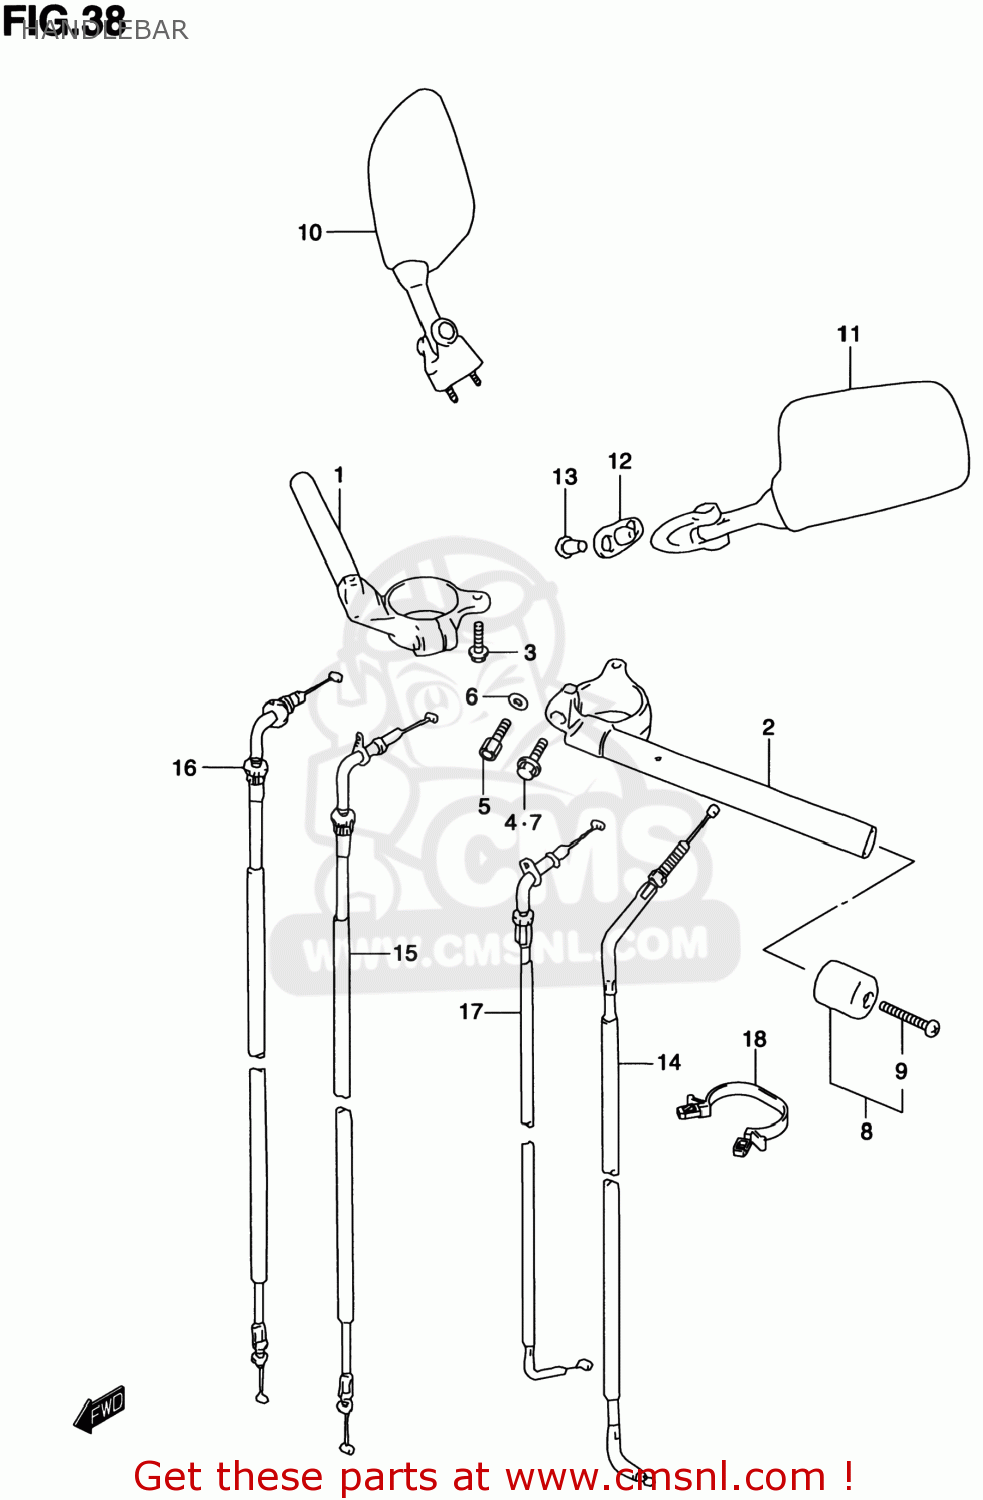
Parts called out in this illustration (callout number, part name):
1	HANDLEBAR,R
2	HANDLEBAR,L
3	BOLT
4	BOLT(8X30)
5	BOLT,HANDLEBAR,L
6	WASHER
7	BOLT(8X30)
8	BALANCER SET,HANDLEBAR
9	SCREW
10	MIRROR ASSY,RR VIEW,R
11	MIRROR ASSY,RR VIEW,L
12	CUSHION,RR VIEW MIRRORR
13	NUT,RR VIEW MIRROR
14	CABLE ASSY,CLUTCH
15	CABLE ASSY,THROTTLE NO.1
16	CABLE ASSY,THROTTLE NO.2
17	CABLE,STARTER
18	CLAMP
